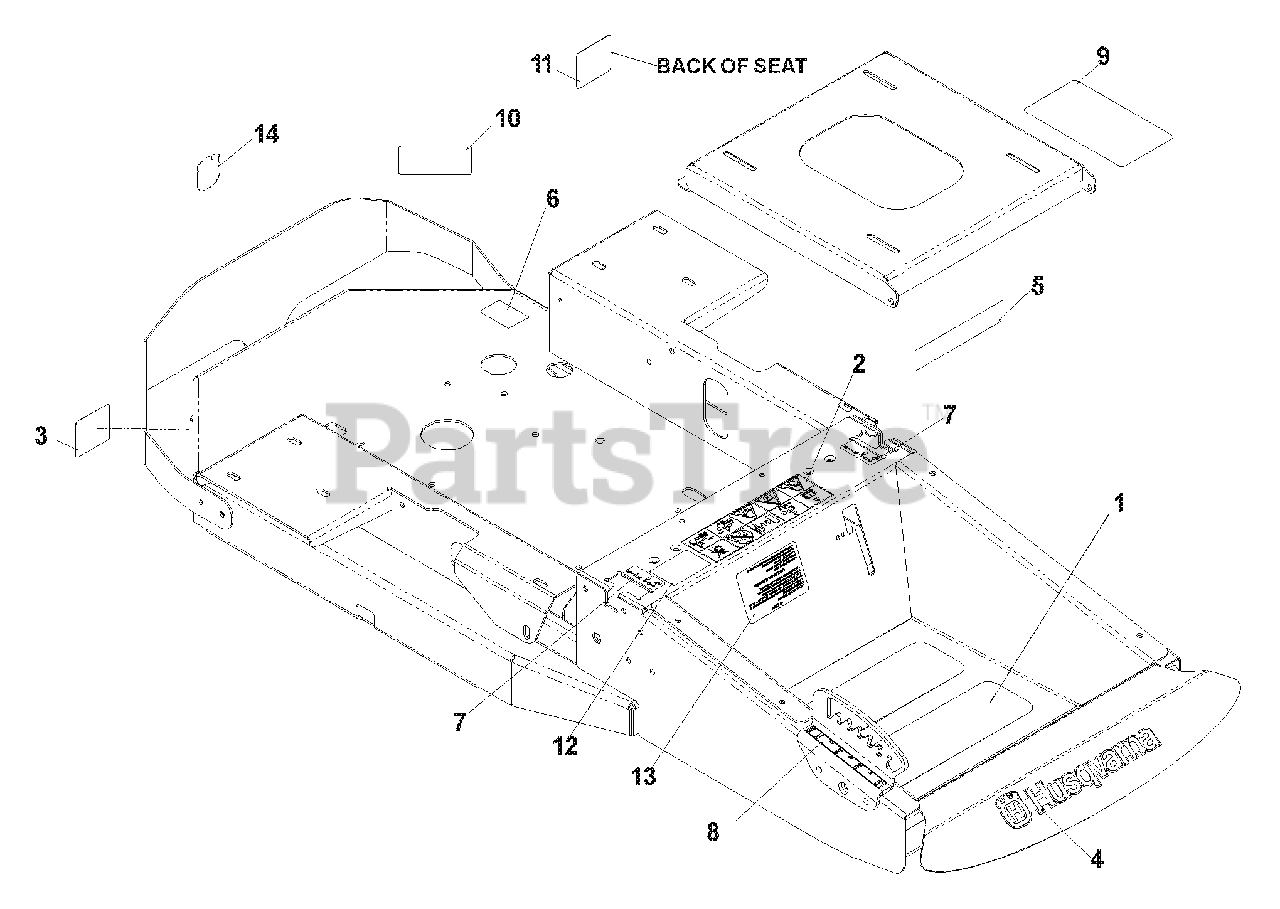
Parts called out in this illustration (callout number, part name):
1	ABRASIVE PAD
2	DECAL, WARNING
3	DECAL, DO NOT TOW
4	DECAL, HUSQVARNA
5	EURO DECAL, BATTERY WARNING
6	DECAL, PROP 65
7	DECAL, MOTION CONTROL
8	DECAL, CUTTING HEIGHT
9	DECAL, SERVICE
10	EURO DANGER DECAL, BELT DRIVES
11	DECAL, SMALL CROWN
12	DECAL, DRIVE LEVER
13	DECAL, START
14	DECAL, CROWN
